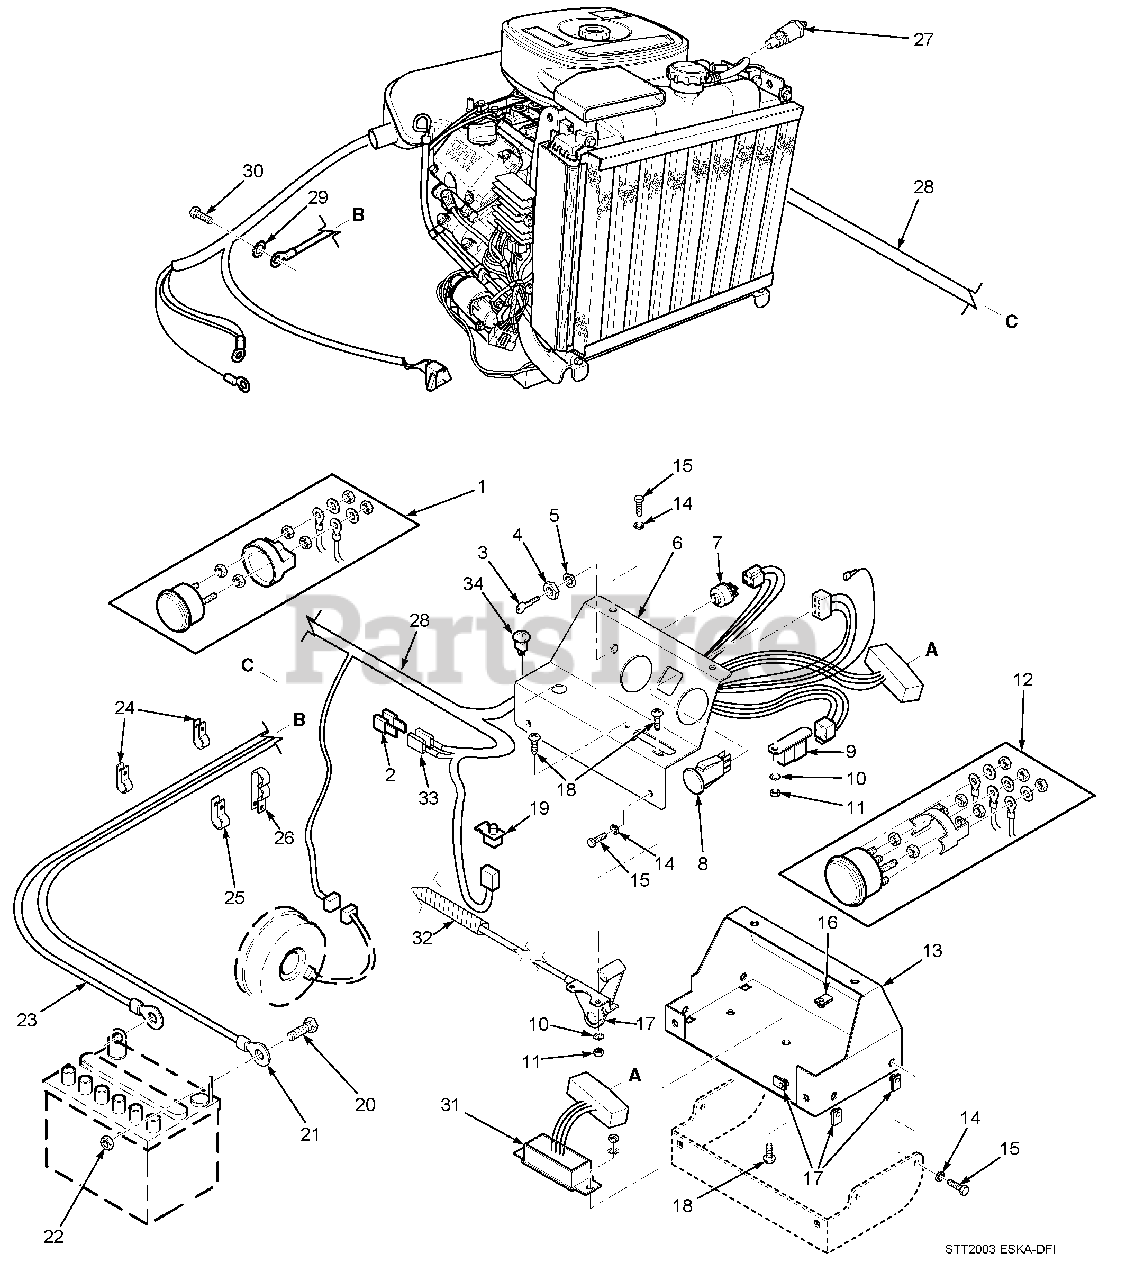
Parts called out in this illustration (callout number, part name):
1	Ammeter
2	Fuse, 20 AMP
3	Key & Ring Assembly
4	Nut, Hex 5/8-32
5	Lockwasher, 5/8" Internal
6	Instrument Panel, Top w/Decals
7	Key Switch
8	Switch, PTO
9	Relay
10	Lockwasher, #10 External Tooth
11	Nut, Hex #10-32
12	Water Temp. Gauge
13	Base, Instrument Panel
14	Lockwasher, 1/4"
15	Bolt, Hex Head 1/4-20 x 3/4"
16	U-Nut, 1/4-20
17	Throttle Controls
18	Screw, Phillips Washer Head #10-32 x 1/2"
19	Switch, Interlock-Seat
20	Bolt, Hex Head 1/4-20 x 1/2"
21	Cable, Battery - Red
22	Nut, Hex 1/4-20
23	Cable, Battery - Black
24	Clamp, Cable 1/2" ID.
25	Clamp, Cable 3/4" ID.
26	Clamp, Cable
27	Sending Unit, Water Temp.
28	Wire Harness, STT Liquid Cooled Digital Fuel Injection (DFI)
29	Lockwasher, 5/16" External Tooth
30	Bolt, Hex Head M8-1.25 x 20
31	Electronic Module
32	Heatshield, Flexible
33	Fuse Holder w/Fuse and Connector
34	Indicator Light, Check Engine
